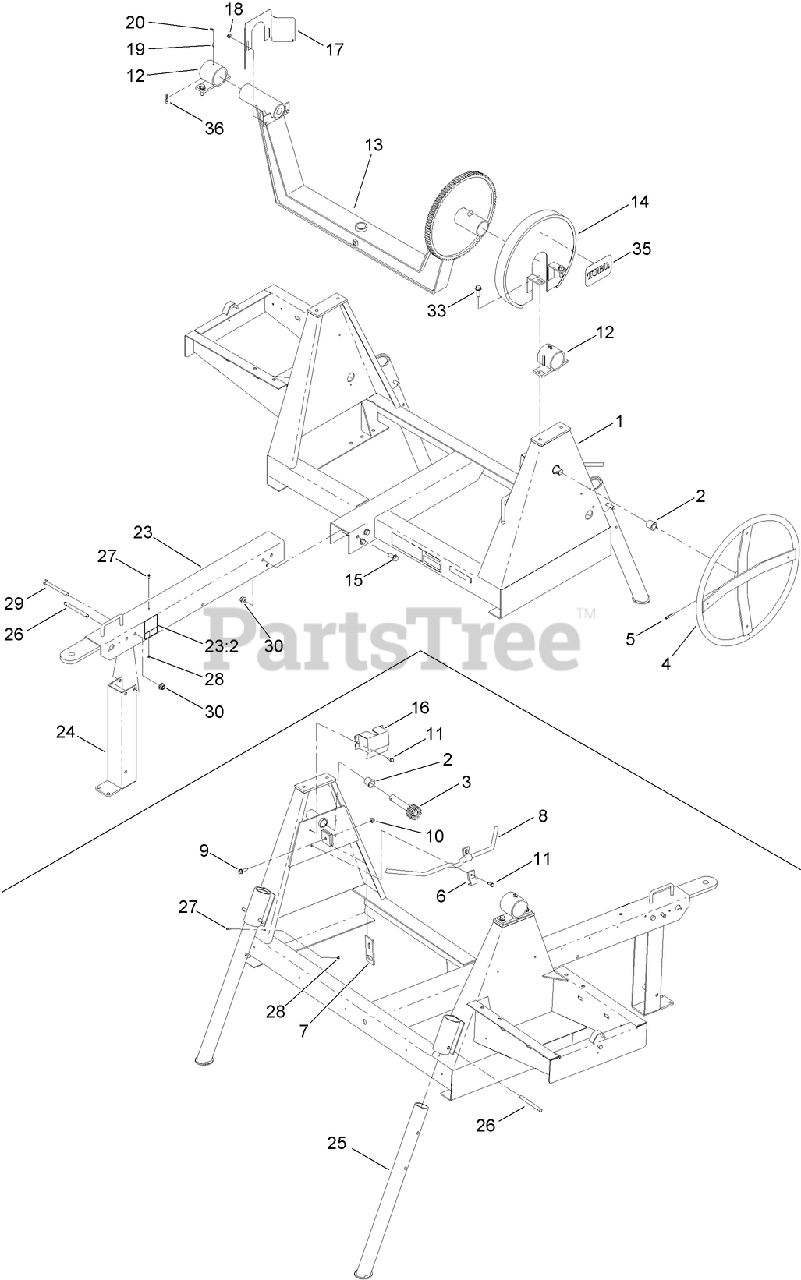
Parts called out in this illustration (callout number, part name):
2	BUSHING-NYLON
3	SHAFT-TILT
4	HANDWHEEL
5	PIN-ROLL
6	BRACKET-HANDLE
7	DOG-BRAKE
8	HANDLE-BRAKE
9	SCREW-HHF
10	NUT-HF, NI
11	SCREW-HWHTF
12	TRUNNION
13	YOKE ASM
14	GUARD-BRAKE, UPPER
15	SCREW-HHF
16	GUARD-BRAKE, LOWER
17	GUARD-PINION
18	NUT-HF, NI
19	FITTING-GREASE
20	CAP-PLUG
23	TOW POLE ASM
23:2	DECAL-SAFETY CHAIN, TOWING
24	POST-FOOT
25	LEG-STABILIZER
26	PIN-CLEVIS, LANYARD
27	SCREW-PPH
28	NUT-LOCK, NI
29	SCREW-HH
30	NUT-LOCK
33	SCREW-HWH
35	DECAL
36	DECAL-GREASE
